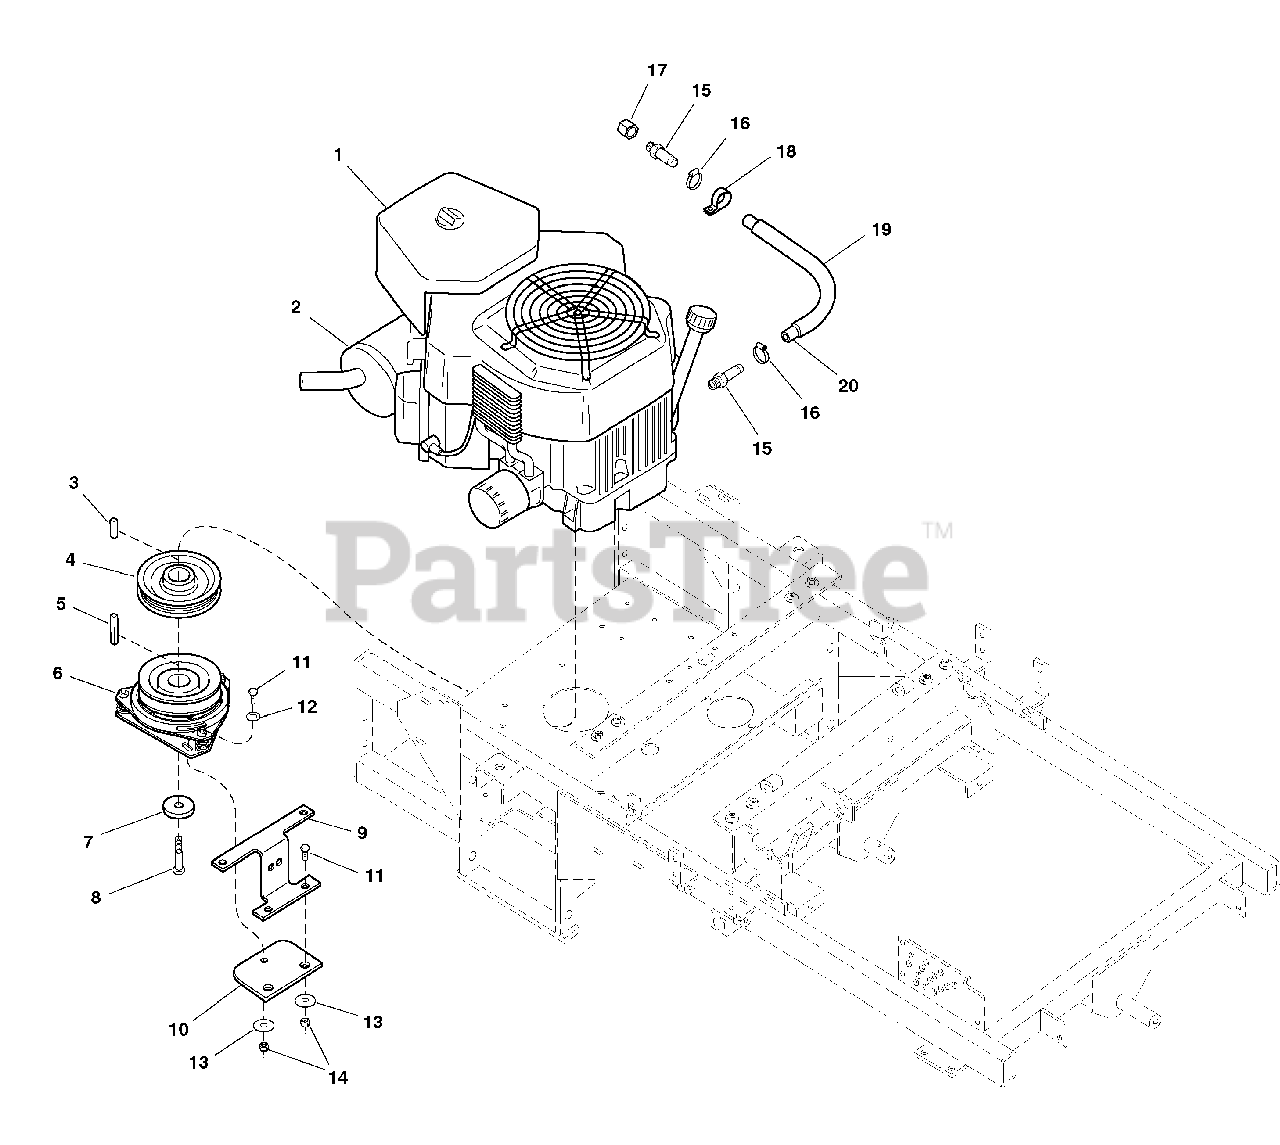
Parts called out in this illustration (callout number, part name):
1	ENGINE, 23 HP Kohler
2	MUFFLER, Kohler
3	KEY, 1/4 x 1
4	PULLEY, Crankshaft
5	KEY, 1/4 x 2
6	ELECTRIC CLUTCH
7	RETAINER, Clutch
8	CRANKSHAFT BOLT, 7/16 x 2-1/4
9	ANCHOR, Clutch
10	PAD, Clutch Anchor
11	CAPSCREW, Hex Hd, 5/16-18 x 3/4
12	WASHER, 5/16
13	WASHER, Fender, 5/16
14	NUT, Hex, Nylon Lock, 5/16-18
15	FITTING, 3/8NPT - 1/2 Str.
17	CAP, 3/8NPT
18	CLAMP, Vinyl
19	WIRE LOOM, Drain Hose Cover
20	HOSE, Oil Drain
